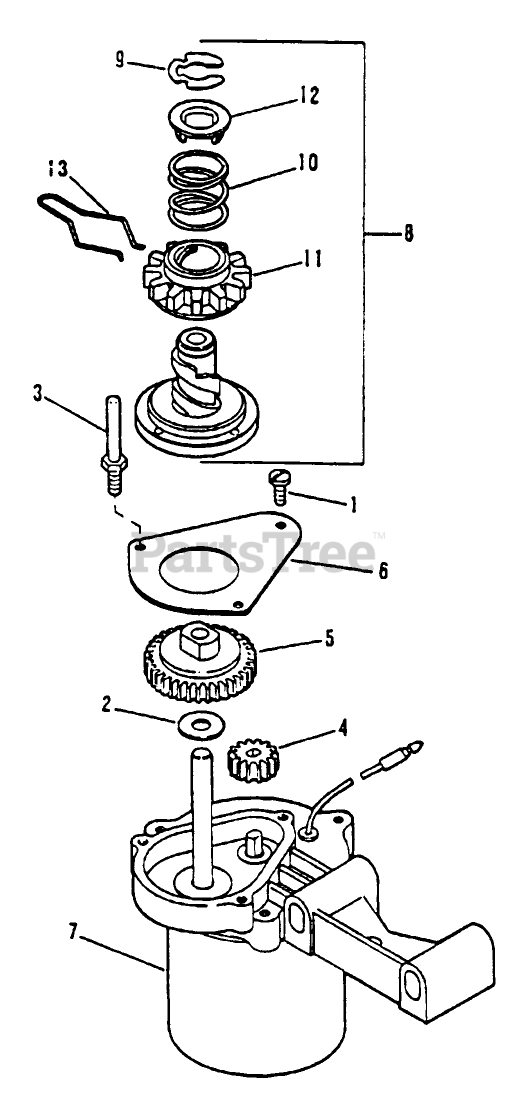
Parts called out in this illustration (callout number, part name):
1	SCREW EF
4	PINION SM
6	GEAR COVER EF
9	RET.RING EF
10	*SPRING PINION EF
11	PINION SM
12	STOP WASHER EF
13	SPRING - DRAG
